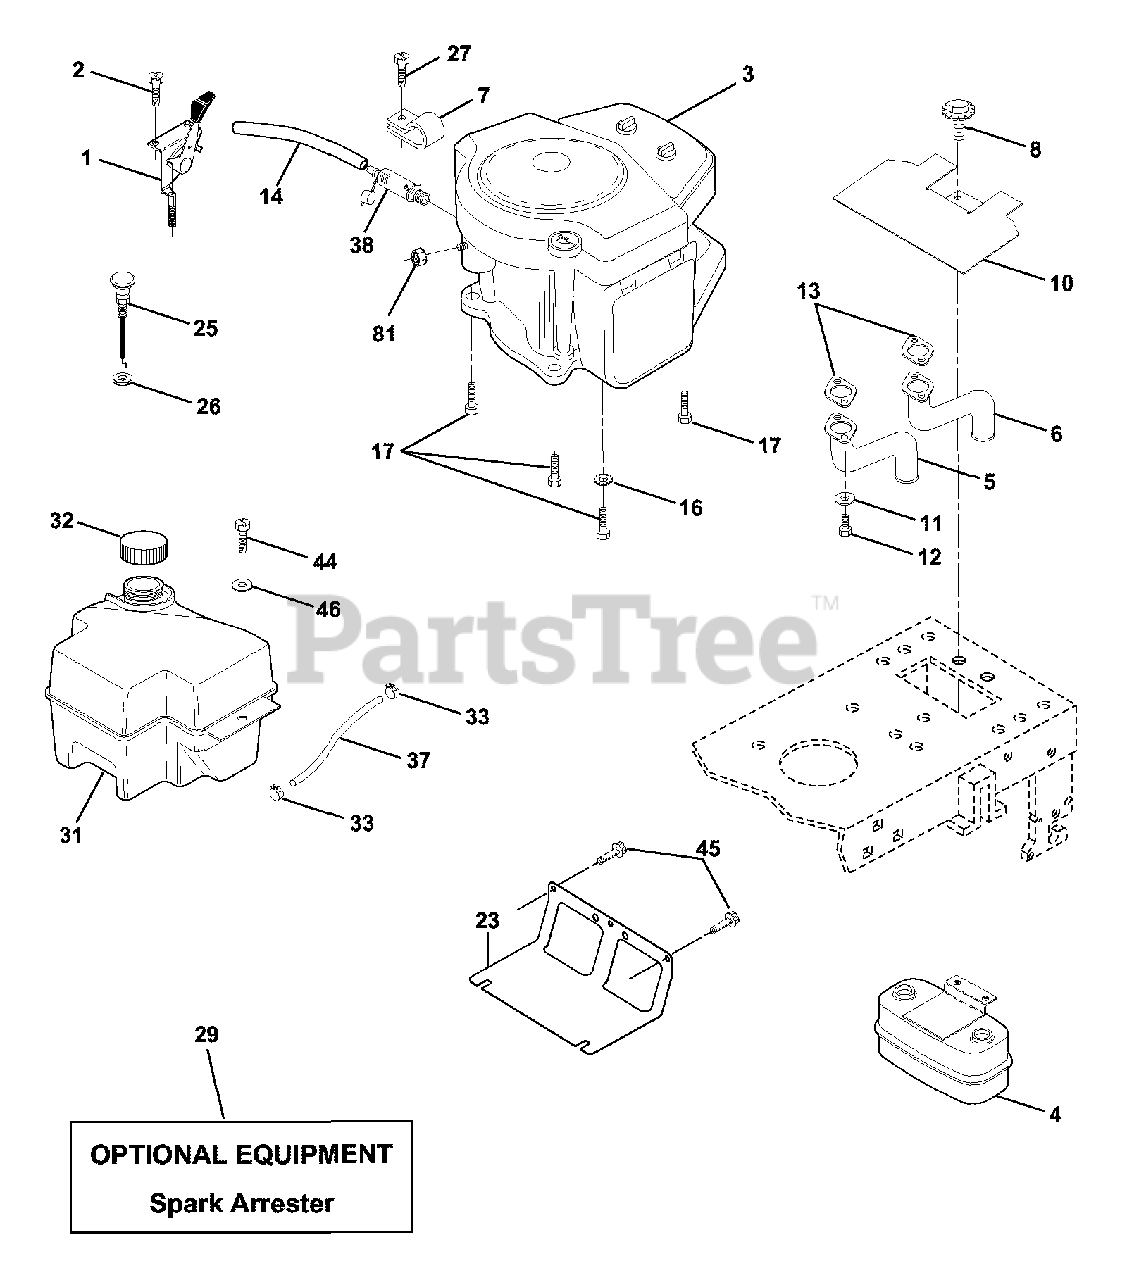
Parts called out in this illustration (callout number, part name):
2	Muffler Side
8	Pulley V-Idler
9	Keeper Asm. Belt Engine VGT
11	Clutch Electric
12	Pulley Engine VGT Elect Clutch
15	Tank Fuel Rear 3.50
16	Pad Spacer
17	Pad Spacer
18	Top Vented N/LANY
20	Control Throttle
21	Screw Hex Thd Cut 1/4 - 20 X 5/8
22	Control Choke
24	Washer Ext Tooth 3/8
25	Nut Keps 3/8-24 Unf
27	Stem Tank Fuel
28	Fuel Line
29	Spark Arrester Kit
35	Washer
37	Clamp Hose
39	Screw TT 3/8-16 x 2-1/4 UNC
40	Screw TT 3/8-16 x 4 UNC
41	Washer 1-1/2 OD X 15/32 ID X .250
42	Washer Lock 7/16
43	Bolt Hex 7/16-20 X 4-1/4 Ga 5
45	Nut Keps Hex 1/4-20
62	Shield Heat Muffler CV-Intek
70	Tube Exhaust LH
71	Tube Exhaust RH
74	Elbow Street Brass
79	Screw Hex Hd Cap 5/16-18 x 3/4
81	Tube Drain Oil Easy
82	Plug Oil Drain Easy
83	Bolt 5/16-18unc X 1-3/4 W/Sems
84	Screw Thdrol 3/8-16 x 1-1/2
